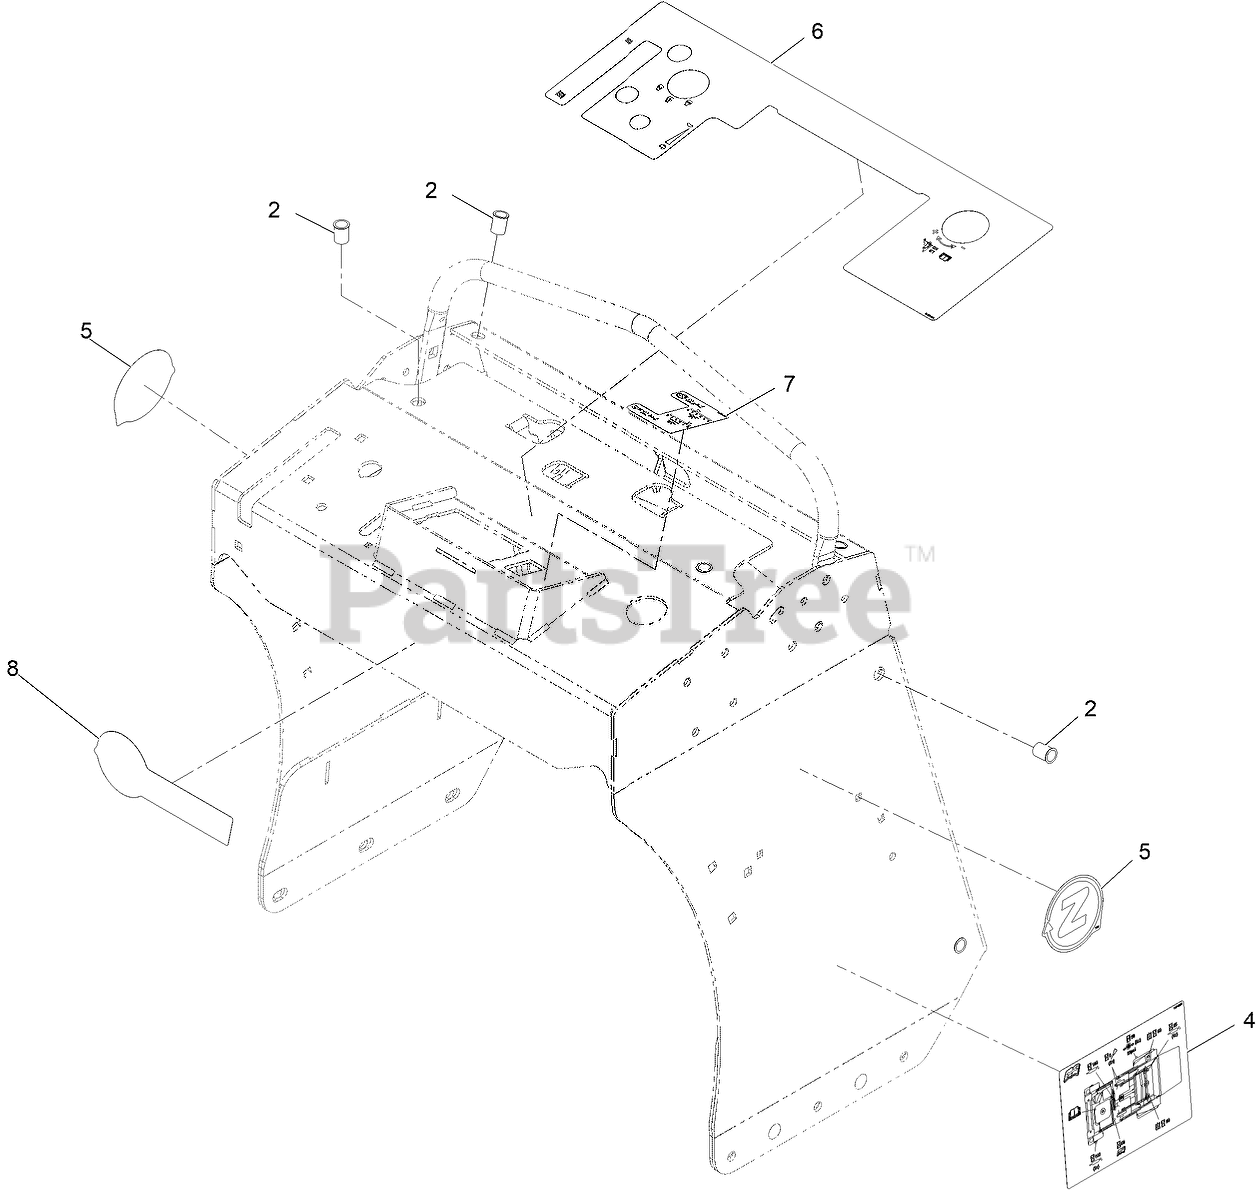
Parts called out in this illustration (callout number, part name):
2	NUT-CLINCH
4	DECAL-AID, SERVICE
5	Decal-Z-Logo
6	DECAL-PANEL, CONTROL
7	DECAL-CONTROL, TINE
8	DECAL-Z-AERATE 24 LOGO
